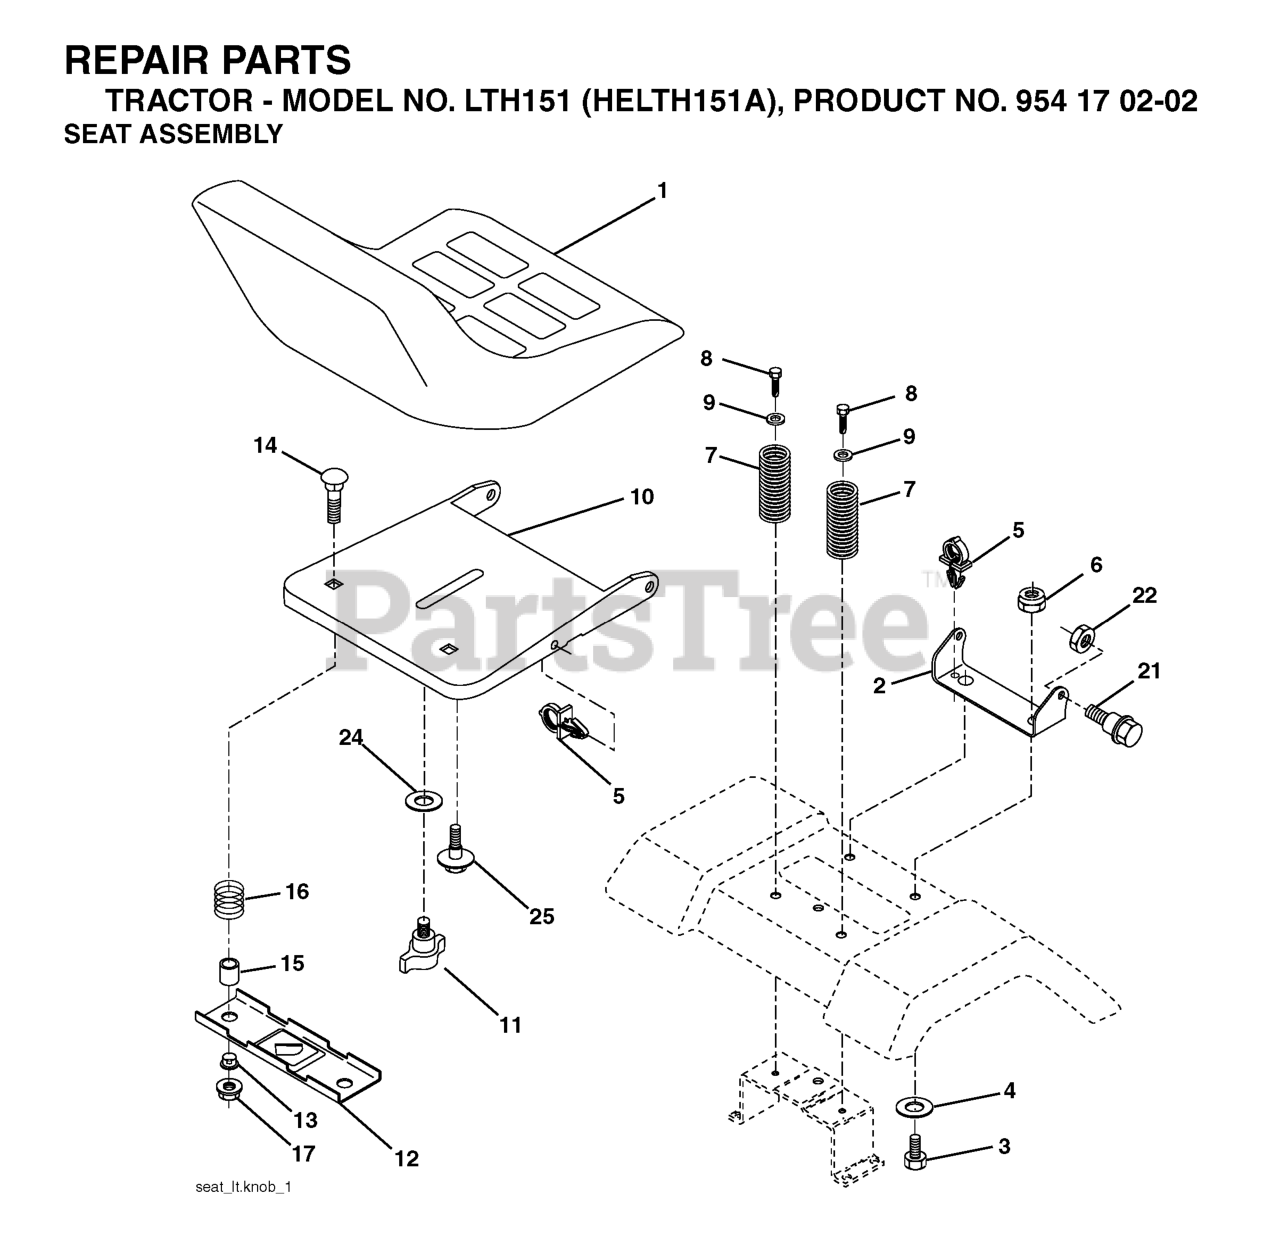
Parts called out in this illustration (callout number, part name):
1	SEAT
2	SEAT PIVOT BRKT
3	BOLT, HEX 3/8-16X1
6	NUT
7	SPRING COMPRESSION
8	SCREW 3/8-16X1
9	WASHER
10	PAN SEAT
11	KNOB.SEAT.ADJ.WINGNUT
12	BRKT SWITCH
14	BOLT.ROUND.HEAD.SQUARE.NECK
15	SPACER SPLIT 28X.96
17	NUT T
21	BOLT.SHOULDER.5/16-18
22	NUT.71038.31-18.HEX.NYLOCK
25	BOLT,SHOULD
